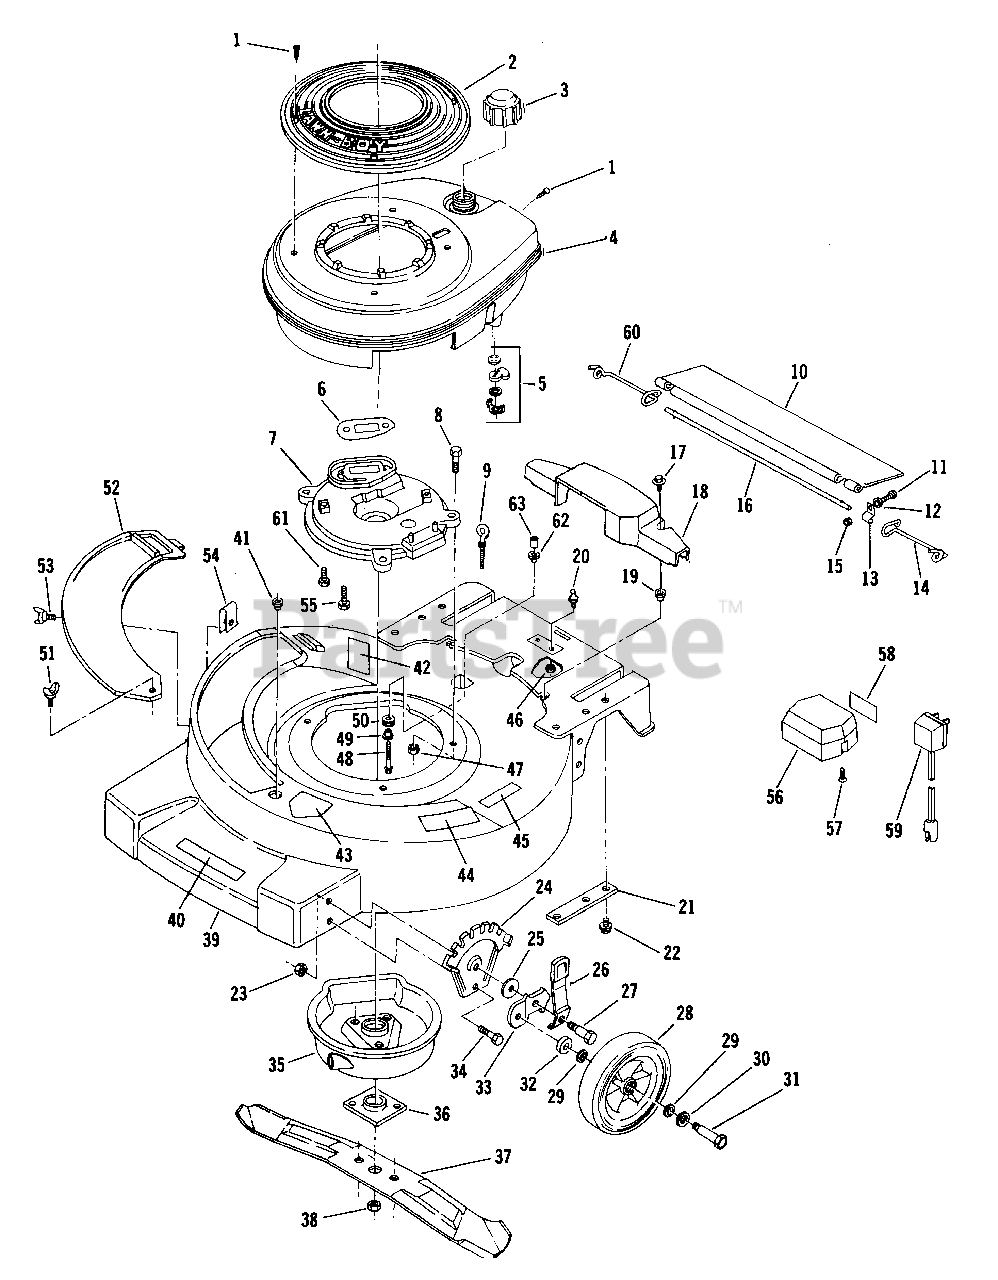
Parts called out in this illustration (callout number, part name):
1	Screw
2	Cover-Shroud
3	Fuel Cap
4	Shroud-Engine
5	Fuel Shut-Off Assembly
6	Gasket-Exhaust
7	Plate-Muffler
8	Screw-Muff. Plt. to Hsg.
9	Eye Bolt
10	Shield-Trailing
11	Screw
12	Washer
13	Clamp
14	Spring-L.H.
15	Nut
16	Rod-Trailing Shield
17	Screw-Axle Cover Mounting
18	Cover-Drive Axle
19	Grommet
20	Ball Stud-Batt. Mounting
21	Plate-Handle Brkt. Support
22	Screw-Handle Bracket to Housing
23	Nut
24	Plate-Height Adjust
25	Washer
26	Knob and Spring Assembly
27	Bolt-Shoulder
28	Wheel-Front
29	Washer-Felt
30	Washer
31	Bolt-Wheel-Front
32	Washer
33	Bracket-Wheel Height Adjustment
34	Screw-Hgt. Adj. Plate
35	Muffler Cover Assembly
36	Collar and Plate Assembly
37	Blade-21"
38	Nut-Blade
39	Housing Assembly
40	Decal-Caution
41	Grommet
42	Decal-Discharge Area
43	Decal-Blade Contact Warning
44	Pad-Starting
45	Decal-Starting Pad
46	Nut-Ball Stud
47	Nut-Muff. Plt. to Housing
48	Screw-Transmission to Hsg.
49	Spacer
50	Grommet
51	Wing Screw
52	Cover Plate
53	Thumb Screw
54	Speed Nut-Cover Plate Mounting
55	Screw-Muff. Plt. to Block
56	Battery Box and Battery
57	Screw
58	Decal
59	Battery Charger Assembly
60	Spring-R.H.
61	Screw-Muffler Plate to Block
62	Spacer
63	Spacer
